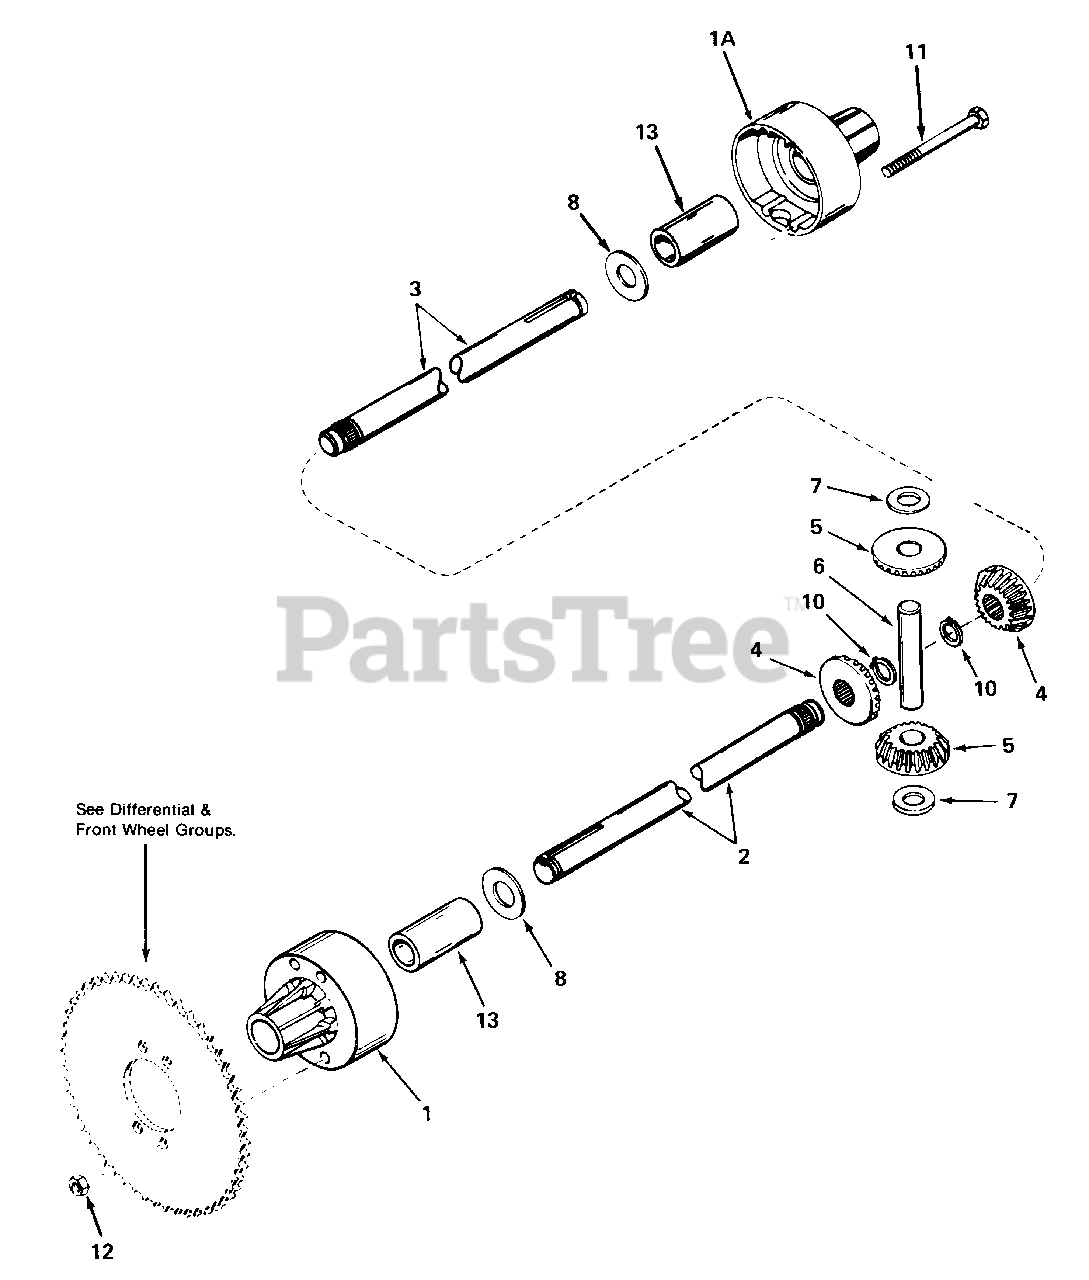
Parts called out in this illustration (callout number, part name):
1	HOUSING, Differential Carrier (Incl. Ref. No. 13)
1A	HOUSING, Differential Carrier (Incl. Ref. No. 13)
2	AXLE (8-63/64" Long)
3	AXLE (22-9/64" Long)
4	GEAR, Bevel
5	GEAR, Pinion
6	PIN, Drive
7	WASHER, Thrust
10	RING, Snap (Pkg. of 2)
11	SCREW, Flanged Hex Hd., 5/16-18 x 3-15/16
12	NUT, Lock, 5/16-18
